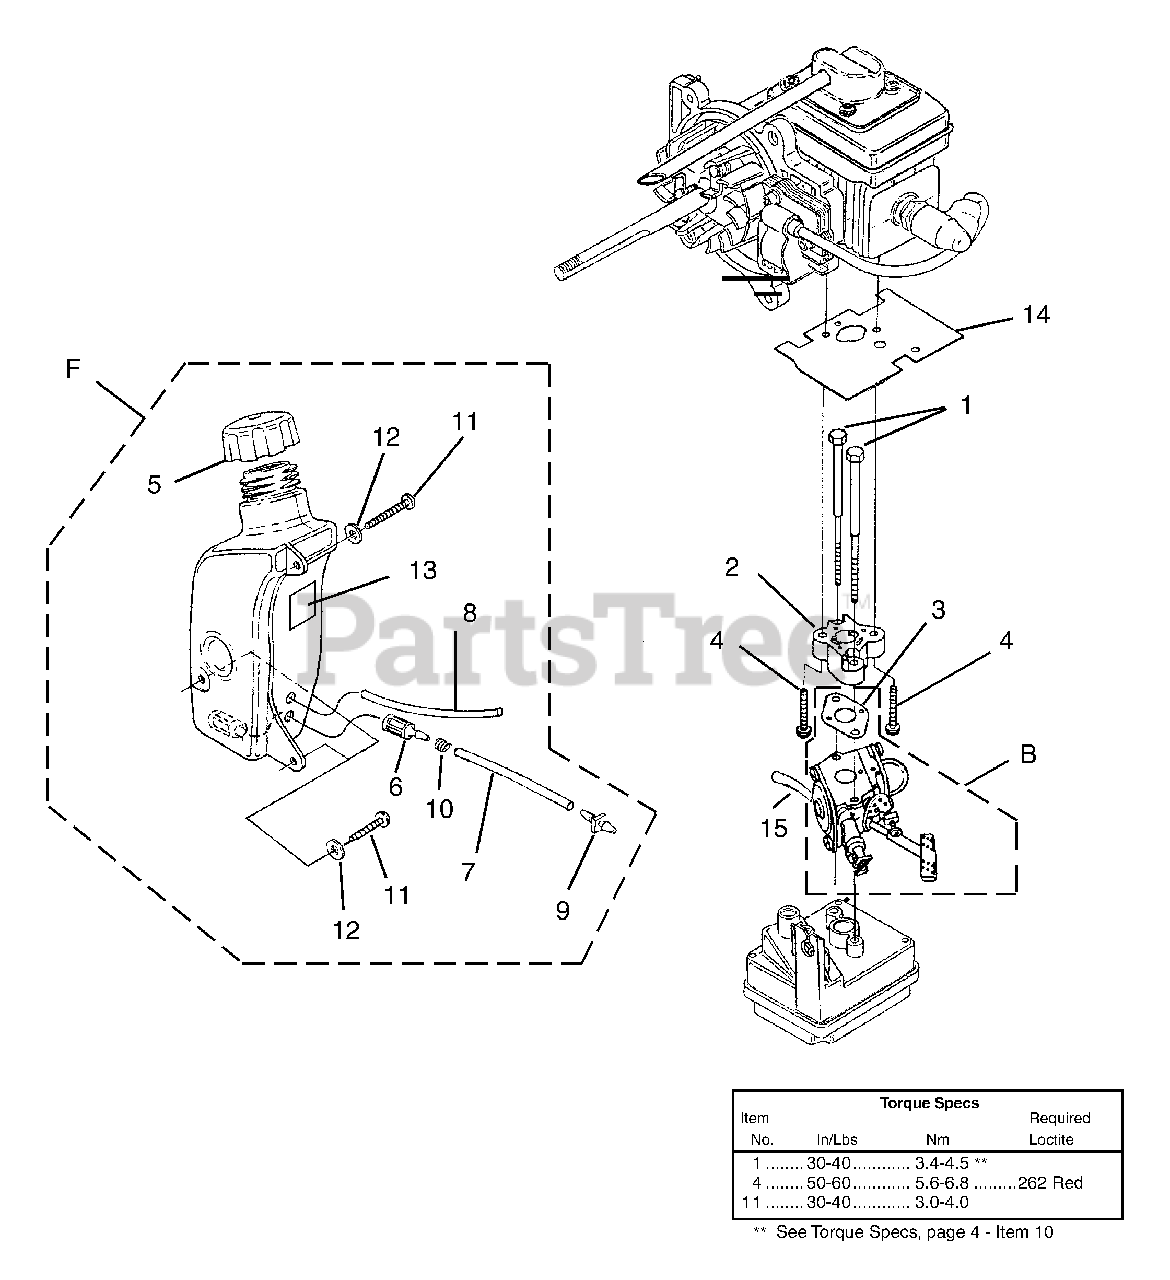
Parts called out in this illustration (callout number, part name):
1	Screw, Machine (10-24 x 2.8)
2	Heat Dam
3	Gasket, Carburetor
4	Screw, Sems (10-24 x 1 in.)
5	Fuel Cap
6	Fuel Filter
7	Tubing, Rubber (3")
8	Tubing, Rubber (5")
9	Fitting, Inlet (small for 2.5mm ID fuel line)
10	Clamp, Wire
11	Screw, Thread Forming (10-14 x 3/4 in.)
13	Heat Shield
14	Gasket, Heat Dam
15	Tubing, Rubber (5")
B	Carburetor Kit
F	Fuel Tank Assy.
